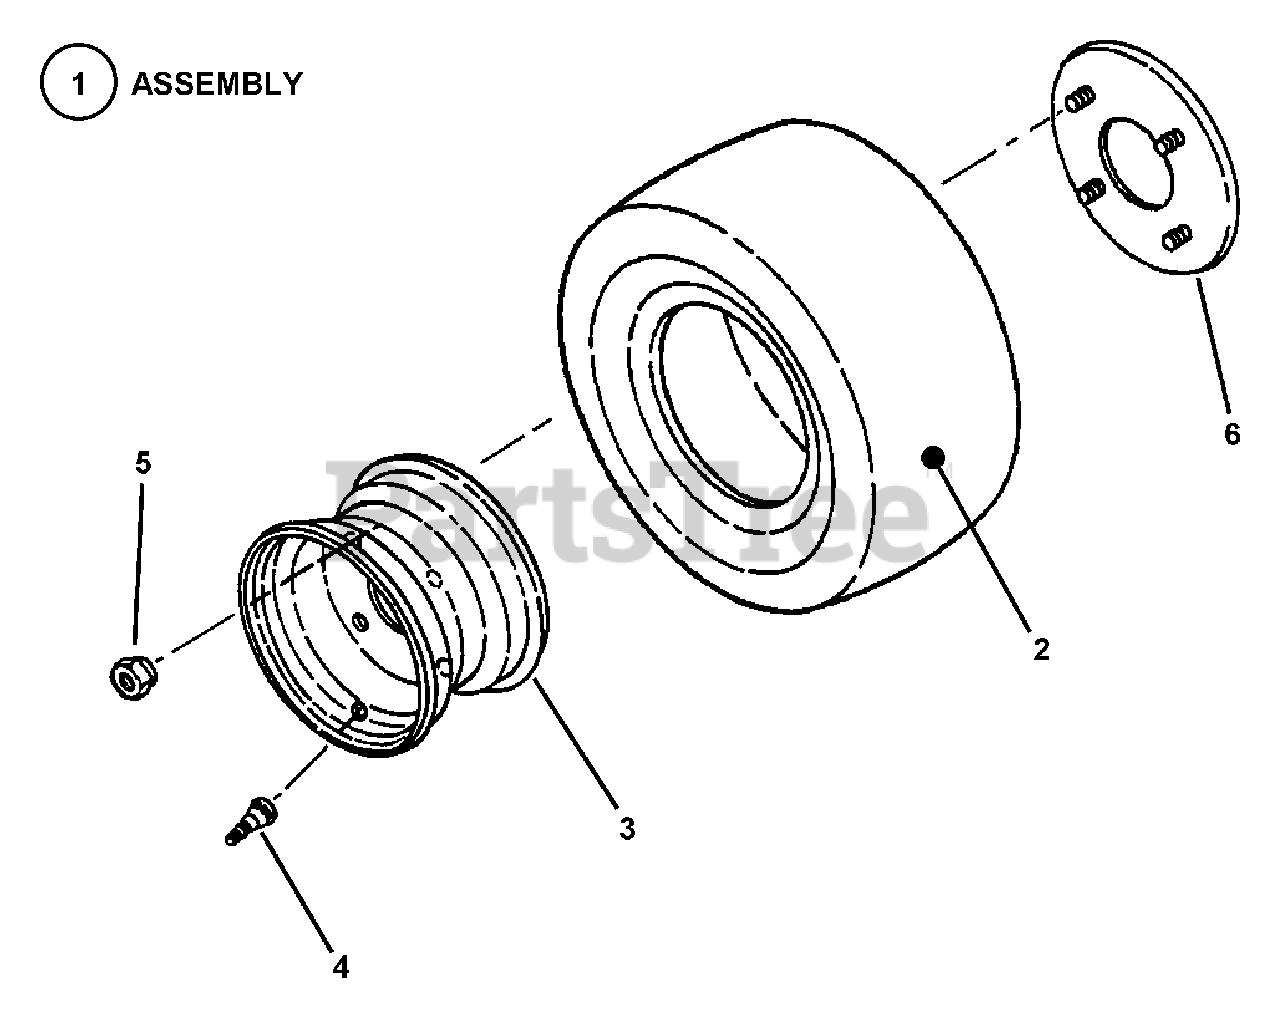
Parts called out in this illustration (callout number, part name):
1	ASSEMBLY, Rear Tire & Rim
2	TIRE, Rear, 16-650 x 8, 4-Ply Tubeless
3	RIM
4	VALVE, Air (Snap-in)
5	LUG-NUT (1/2-20 tapered seat)
